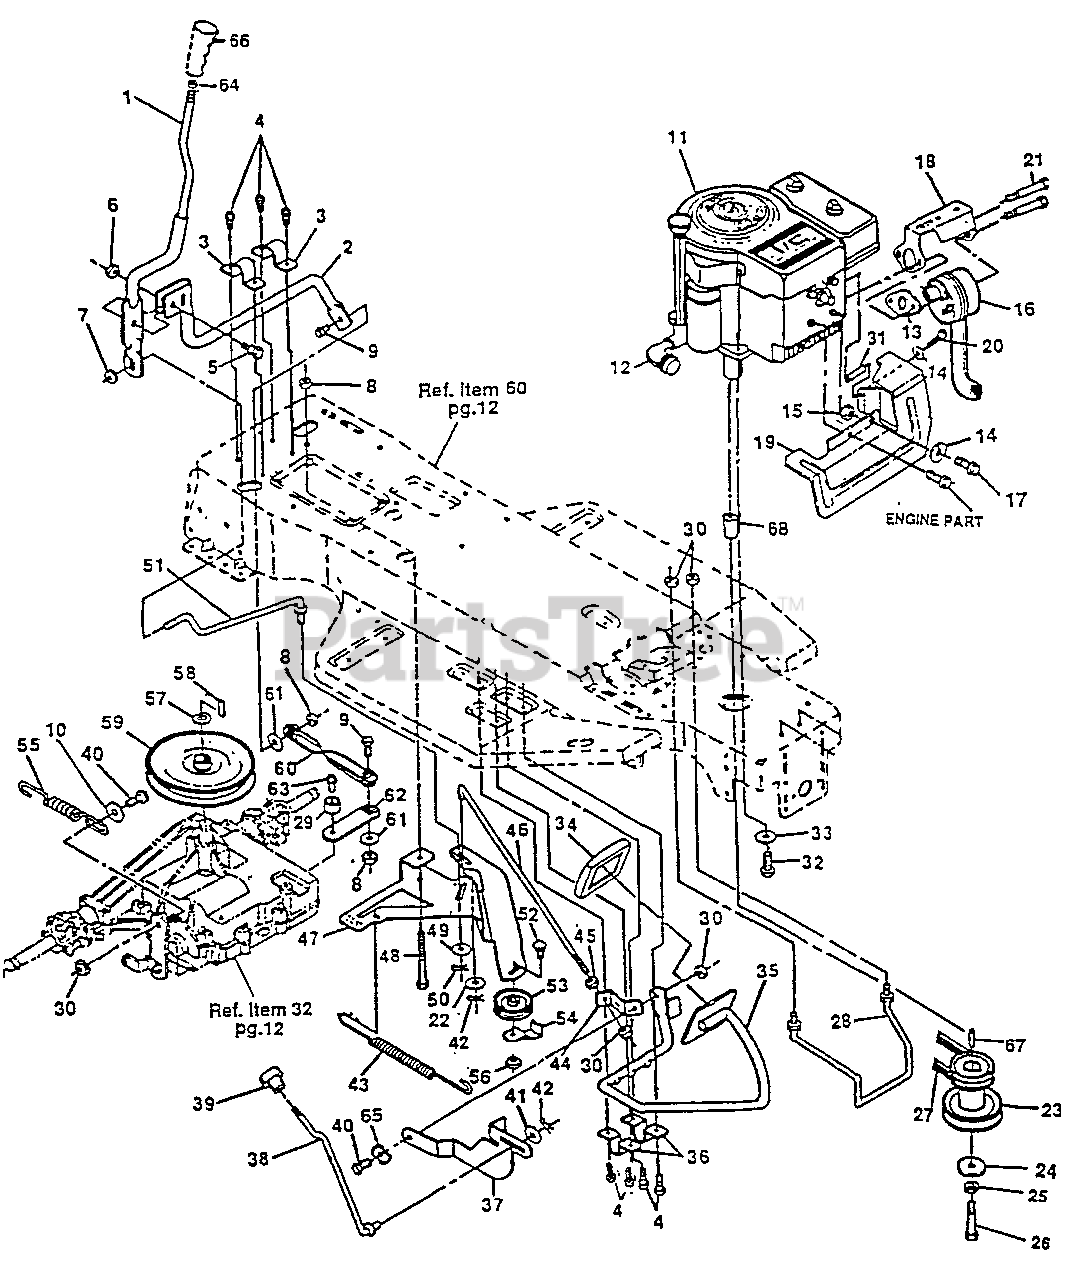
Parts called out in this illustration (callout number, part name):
1	Tube Assembly, Shift Pivot
2	Tube Assembly, Shift
3	Clip, Shift Lever
4	Screw, Hx Hd, Wshr Tap 5/16-18 x 1/2 In.
5	Shoulder Bolt
6	Nut, Hx, Ctrlk, 1/4-20 Thd.
7	Nut, Hx, Nylon, Lock 3/8-16 Thd.
8	Nut, Hx, Ctrlk, 3/8-16 Thd.
9	Screw, 3/8-16 x 1-1/4 In.
11	Engine 12.5 Horsepower B&S
12	Elbow, 90°, 3/8 In.
13	Gasket, Muffler
14	Washer, Split Lock
15	Nut, Hex 5/16-18 Thd.
16	Muffler, Round 5" Diameter
17	Screw, Wa Tap, 1/4-20 x 7/8 In
18	Shield, Muffler
19	Heat Shield, Engine
20	Screw, Hex Hd, 1/4-20 x 3-1/2 In.
21	Bolt, Shoulder, 5/16-18 x 4-1/3 In.
22	Flatwasher, .281 Idx.63 Od
23	Pulley, Engine
24	Washer, Pilot
25	Washer, Split, Lock 7/8 In.
26	Screw, Hx Hd, 7/16-20 X 5 In.
27	V-Belt, 90 In. Long
28	Belt Guide
29	Washer, Special
30	Nut, Hex, Ctrlk, 5/16-18 Thd.
31	Spacer, Heat Shield
32	Screw, Hex Hd Tap, 3/8-16 x 1-1/4 In.
33	Washer, 3/8 In.
34	Pad, Clutch/Brake, Molded
35	Assembly, Clutch/Brake Arm
36	Bracket, Clutch/Brake Arm
37	Lever, Park Brake
38	Rod, Parking Brake
39	Knob, Parking Brake
40	Shoulder Bolt, 5/16-18 Thd.
41	Washer, 9/16 In.
42	Cotter Pin
43	Spring, Clutch
44	Bracket, Brake Rod
45	Nut, Hx, Keps, 5/16-18 Thd.
46	Rod, Clutch
47	Arm, Idler
48	Shoulder Bolt, 3/8-16 Thd.
49	Washer, Flat, 13/32 In.
51	Rod, Shift-On-The-Go
52	Carriage Bolt, 3/8-16 x 2 In.
53	Idler Sheave, Backside
54	Belt Retainer
55	Spring, Brake
56	Nut, Flange, 3/8-16 Thd,
57	Retaining Ring
58	Key, Woodruff, #606
60	Shift Link
61	Washer, Flat, 13/32 In.
62	Shift Lever, Transaxle
63	Screw, Hx Hd, 1/4-28 X 3/4 In.
64	Nut, 3/8-16 Reg Hx
65	Washer, Wave
66	Handle, 3/8-16 Molded Grey
67	Key, Square 1/4
68	Spacer, Engine Pulley
